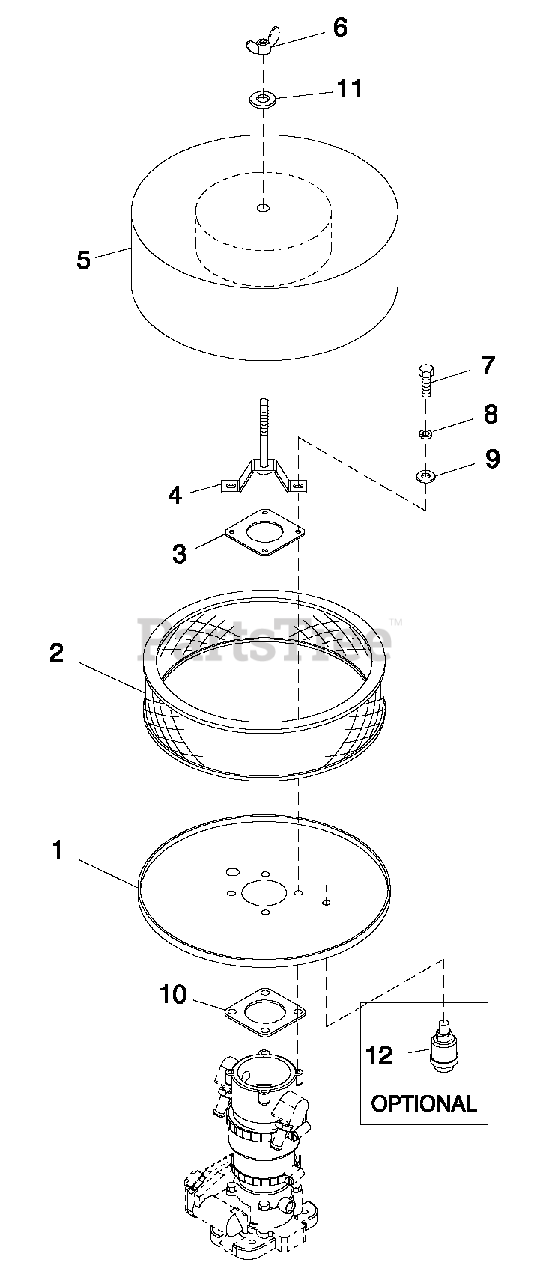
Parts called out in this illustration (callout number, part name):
1	AIR CLNR BTM PLT W/CPLR 8.1L
2	ELEMENT AIR FILTER
3	TOP PLATE VENTURI
4	HOLD DOWN AIR CLEANER PLATED
5	PLATE AIR CLEAN TOP 5.4L/6.8L
6	NUT WING 1/4-20 NYLK
7	SCREW HHC M6-1.0X 16 G8.8
8	WASHER LOCK M6-1/4
9	WASHER FLAT M6
10	GASKET MIXER BODY
11	WASHER FLAT 1/4-M6 ZINC
12	INDICATOR FILTER MINDER
